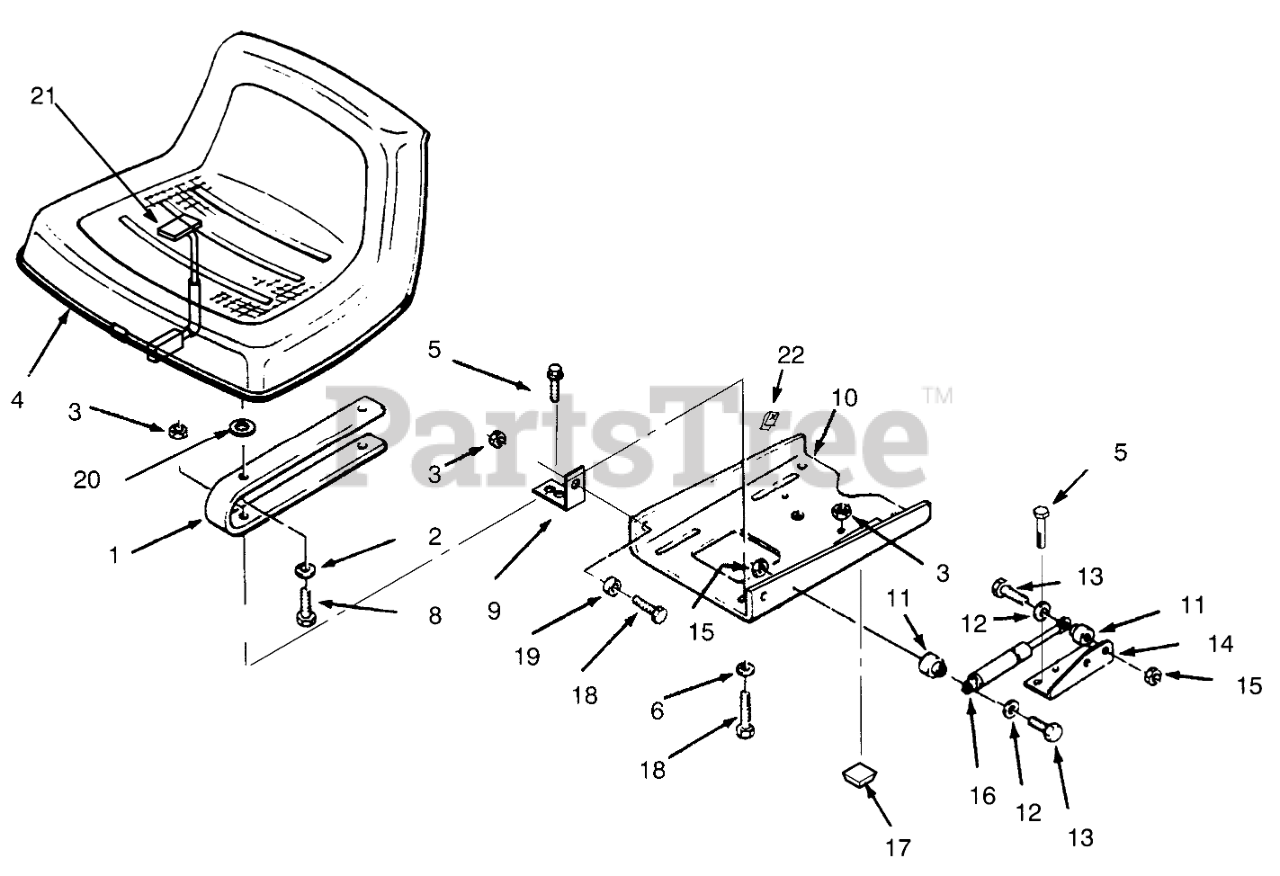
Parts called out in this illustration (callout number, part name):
1	Seat Spring
2	WASHER-LOCK
3	NUT-LOCK, NI
4	SEAT V-410
5	SCREW
6	WASHER-PLAIN
8	SCREW-HH
9	BRACKET-PIVOT
10	Plate-SeatPivot
11	SPACER
12	WASHER-FLAT
13	SCREW-HH
14	BRACKET-CYLINDER R
15	NUT-LOCK, NI
16	GAS SPRING
17	BUMPER SJ5514 BLACK
18	SCREW-HH
19	BUSHING
20	SPACER-NYLON
21	SWITCH-SEAT
22	SPEED CLIP
